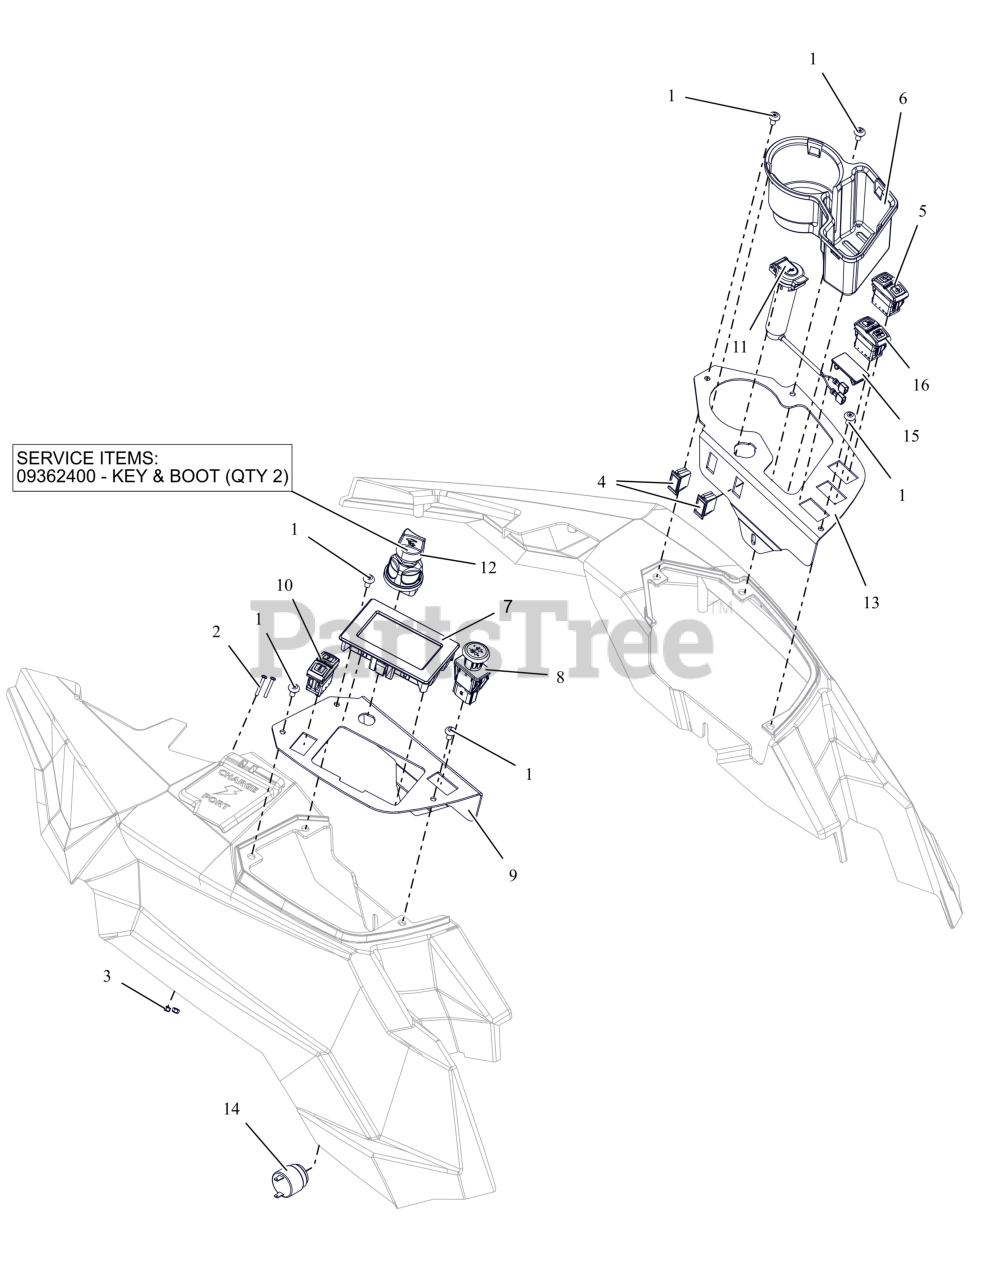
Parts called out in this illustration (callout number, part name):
1	SCR, MCH .25-20 X .500 TXTR ZB500
2	SCR, PH PAN HD #6-32X1.000 ZCC
3	@NUT-LK-NYL 6-32 W/INSRT YWZC
4	SWITCH,BLANK
5	SWITCH, TOGGLE - SPEED
6	HOLDER, CUP
7	DISPLAY, PTEV
8	SWITCH, PTO - RED
9	PANEL, CONTROL -RH (ORANGE)
10	SWITCH, ROCKER - DISPLAY
11	PLUG, CHARGER USB
12	SWITCH, KEY (SEALED)
12	KEY & BOOT (Qty 2)
13	PANEL- LH CONTROL
14	ALARM, AUDIBLE
15	PLUG, SWITCH
16	SWITCH, TOGGLE ECO
